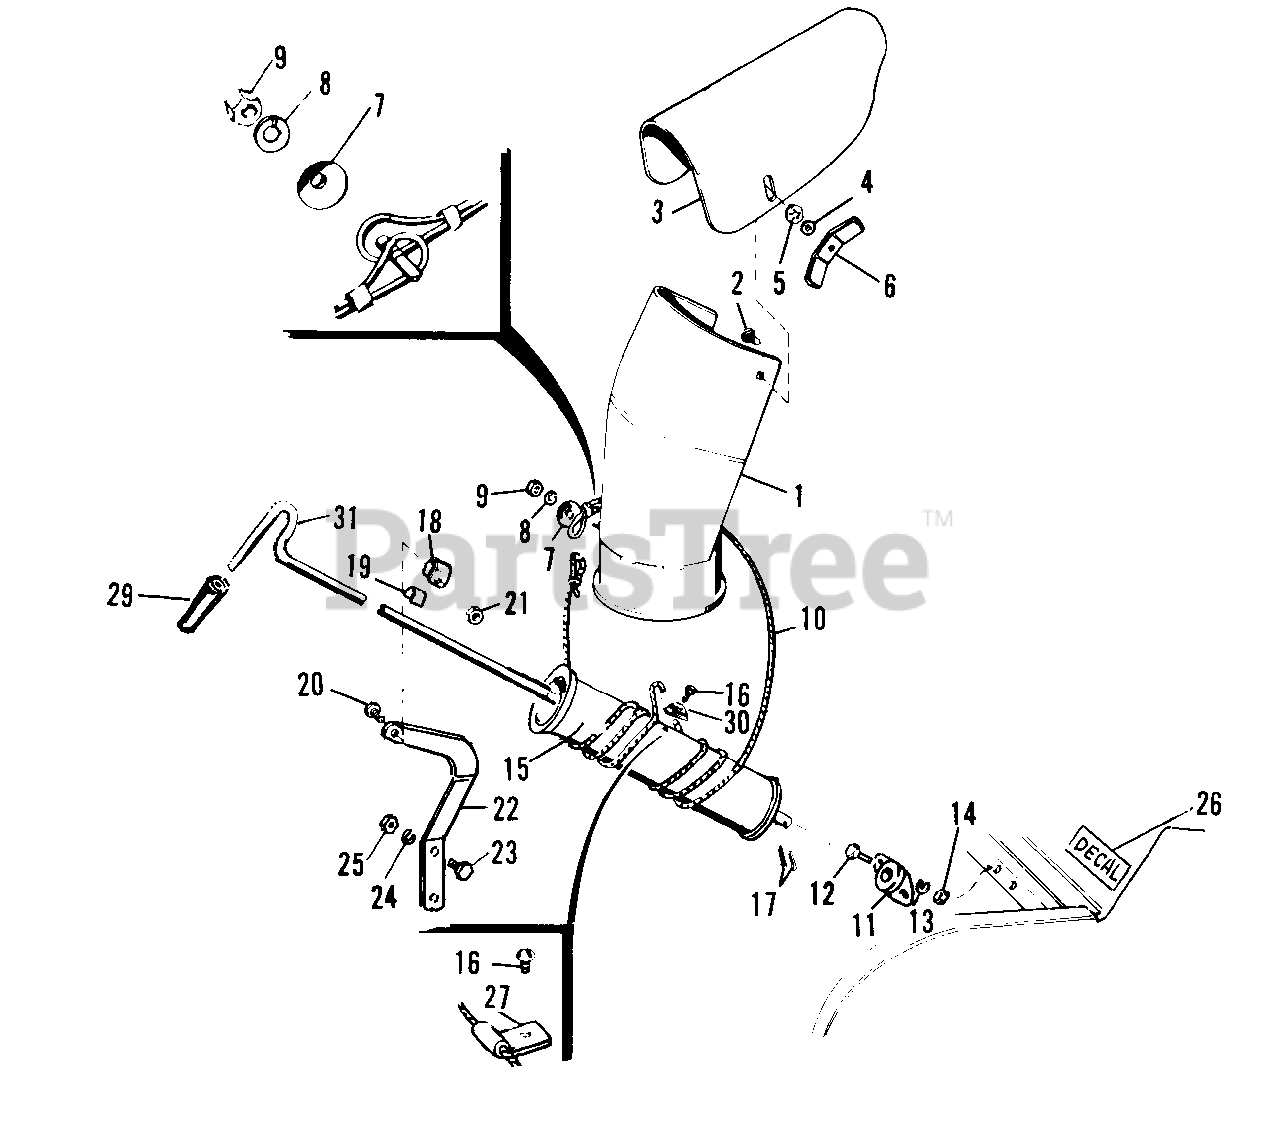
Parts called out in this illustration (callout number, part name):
1	SPOUT ASSEMBLY
2	BOLT, Carriage, 5/16-18 x 3/4
3	SPOUT, Extension
4	WASHER, Plain, 3/8
5	LOCKWASHER, 3/8
6	NUT, Wing, 5/16-18
7	WASHER, Cup
8	LOCKWASHER, 5/16
9	NUT, Full hex, 5/16-18
10	CABLE ASSEMBLY
12	CAPSCREW, Hex, 1/4-20 x 5/8
13	LOCKWASHER, 1/4
14	NUT, Full hex, 1/4-20
15	ROD ASSY., Spout ControI
16	SCREW, Self-tapping 1/4-20 x 3/8
17	PlN, Cotter, 3/32 x 5/8
19	GUIDE, Liner
20	CAPSCREW, Hex, 5/16-18 x 1-1/2
21	NUT, Lock, Full hex, 5/16-18
22	ROD GUIDE SUPPORT
23	CAPSCREW, Hex, 3/8-16 x 1" lg.
24	LOCKWASHER, 3/8
25	NUT, full hex, 3/8-16
27	CLAMP (For Service Only)
28	GRIP, Handle
29	PlN, Cotter
31	HANDLE, Rod
